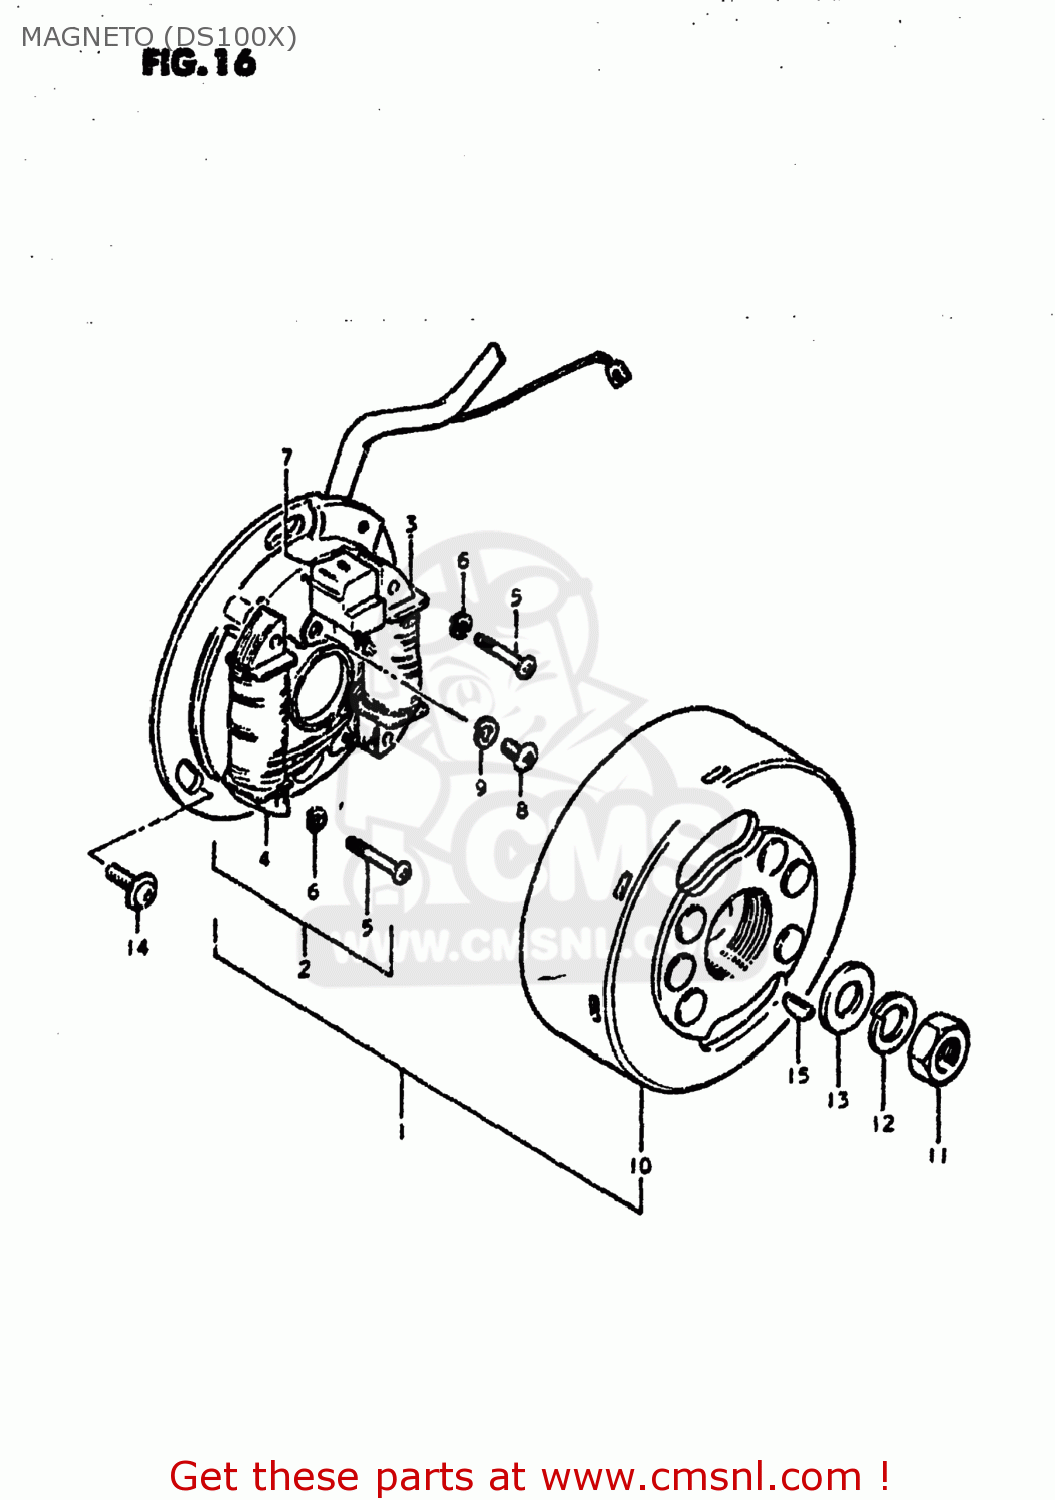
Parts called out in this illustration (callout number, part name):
1	MAGNETO ASSEMBLY
2	STATOR ASSEMBLY
3	COIL,LIGHTING
4	COIL
5	SCREW
6	LOCK WASHER
7	COIL,PULSER
8	SCREW
9	LOCK WASHER
10	ROTOR,FLYWHEEL
11	NUT (10MM)
12	LOCK WASHER
13	WASHER
14	SCREW(5X14)
15	KEY
